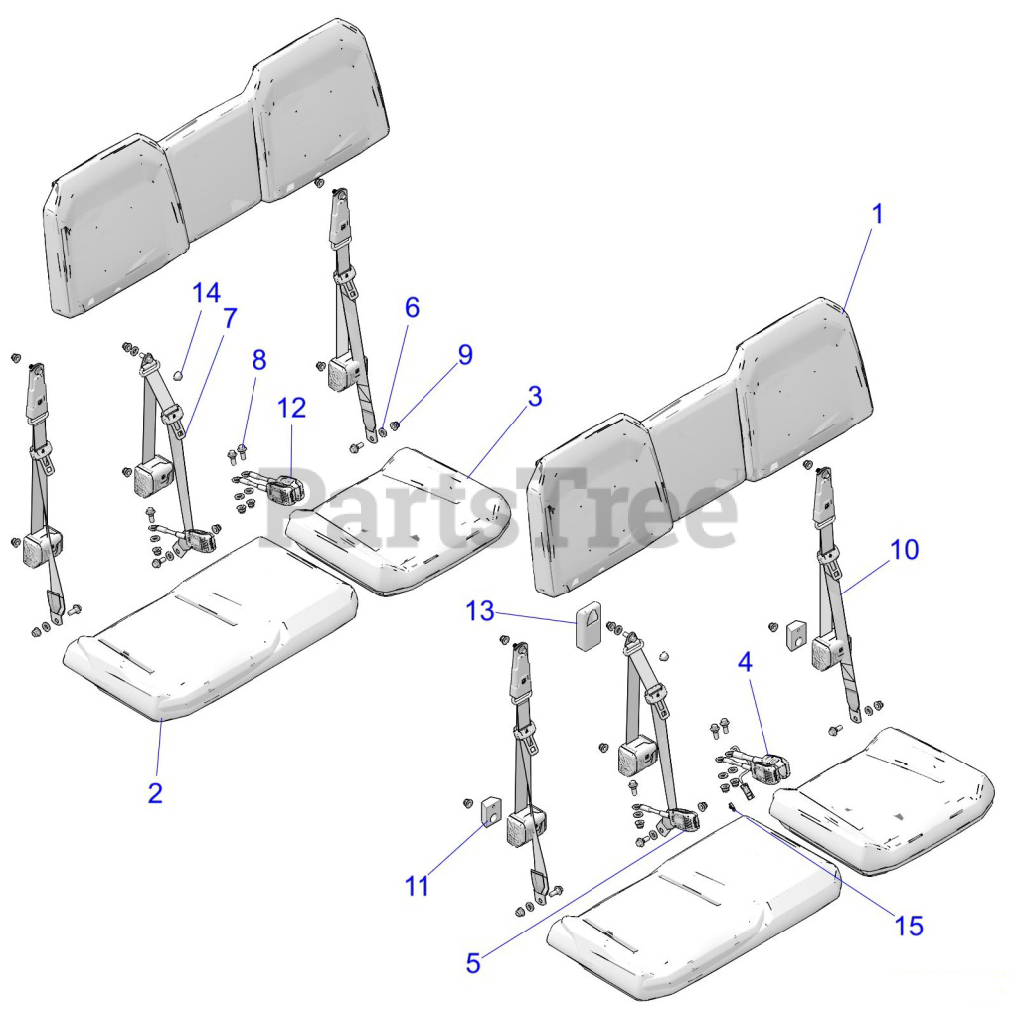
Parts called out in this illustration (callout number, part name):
1	ASM-SEAT-3PASS-BACK-GUNMETAL
2	ASM-SEAT-BTM-60-VINYL-GUNMETAL
3	ASM-SEAT-BTM-40-VINYL-GUNMETAL
4	BUCKLE- SEATBELT- 90- SWITCH
5	BUCKLE-SEATBELT-9.6-PASSENGER
6	WASHER-SEATBELT-RUBBER
7	ASM-SEAT BELT-3PT-CENTER
8	SCR-HXFLSH-M12X1.75-M14X9 ZOD
9	NUT-HXFL M12X1.75 NYLOC ZOD
10	ASM-SEAT BELT-3PT
11	PAD-REAR-SEAT BASE
12	BUCKLE-SEATBELT-9.6-DRIVER
13	COVER-SEAT BELT MOUNT
14	CAP-BOLT HEAD
15	CLIP-CONNECTOR- 6.35 MM HOLE
